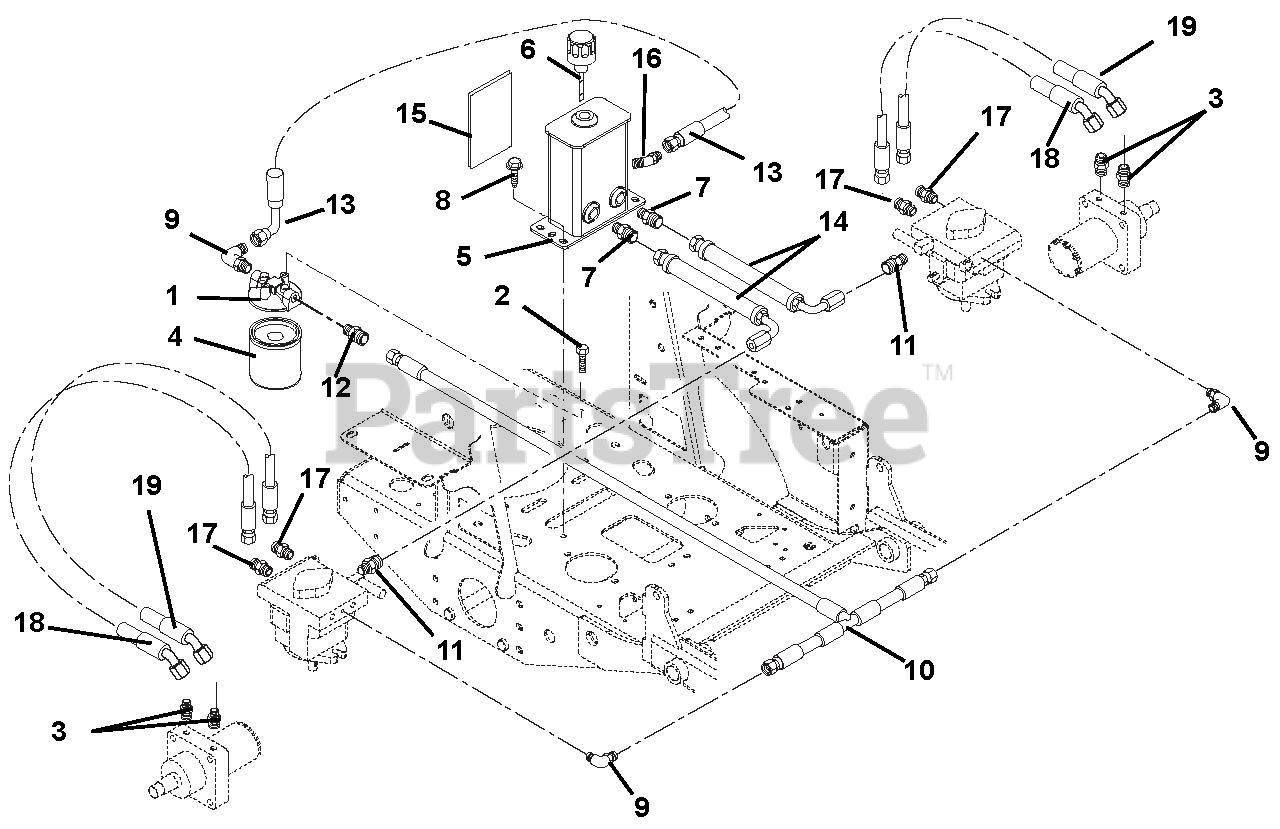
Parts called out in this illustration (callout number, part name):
1	Head, Filter
2	Bolt, Hex .25-20 x .50 Grade 5
3	Adapter, Hydraulic
4	Oil Filter
5	Tank, Hydraulic
6	Breather Dipstick
7	Fitting, Hydraulic Straight M8O-M4F
8	Screw, Tapping .38-16 x .50 Hex Washer Head
9	Fitting, Hydraulic
10	Hose, Hydraulic
11	Fitting, Hydraulic
12	Fitting, Hydraulic
13	Hose, Hydraulic
14	Hose, Hydraulic
15	Shield, Heat 5.50 x 4.50
16	Fitting, Hydraulic 45 Degree
17	Fitting, Hydraulic
18	Hose, Hydraulic .50-11-3K
19	Hose, Hydraulic .50-12-3K
